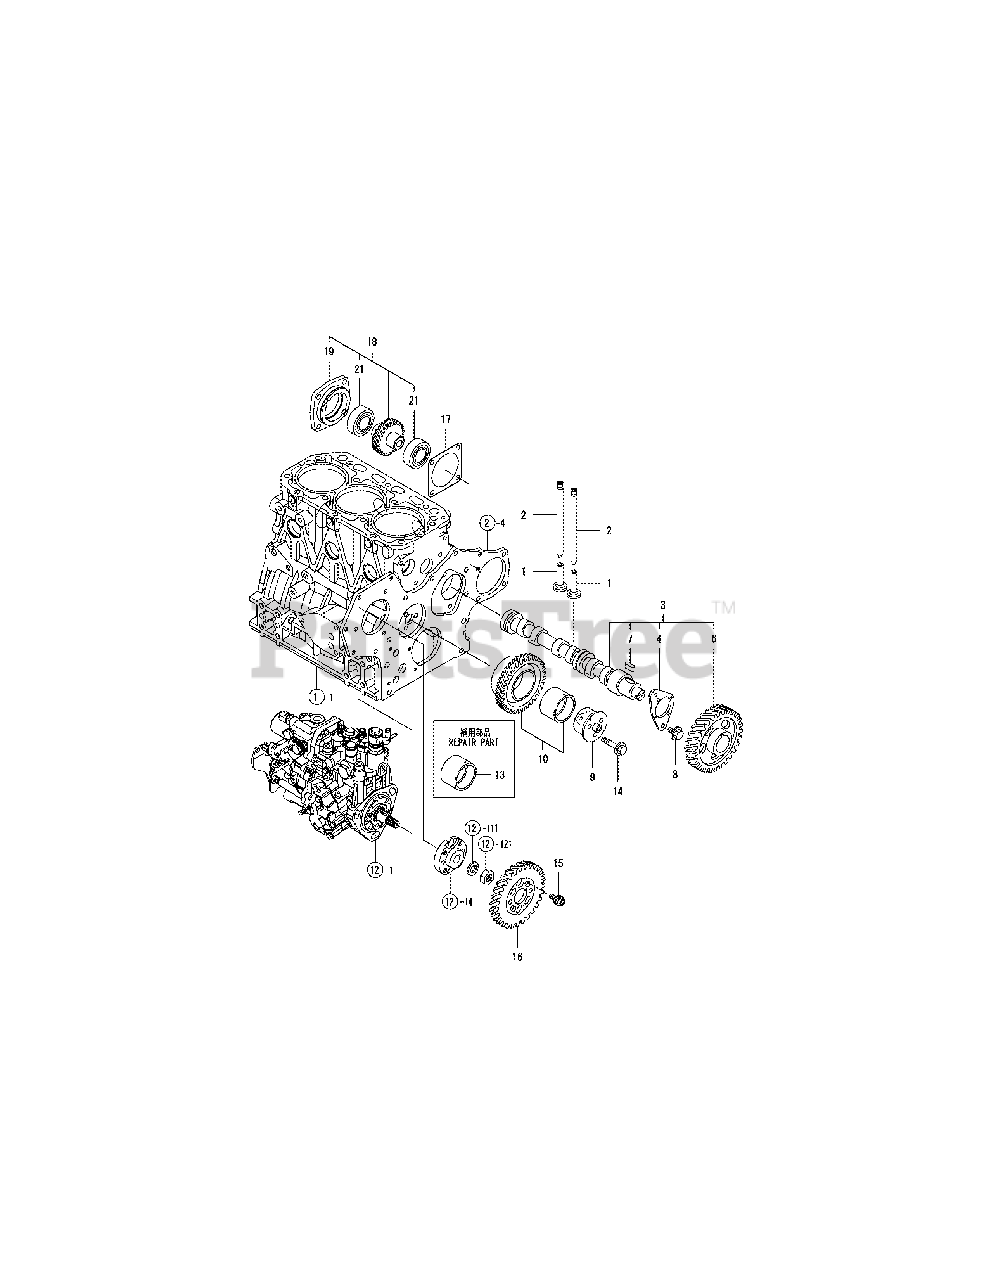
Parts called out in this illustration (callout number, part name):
6	GEAR, CAMSHAFT
8	BOLT 8X 14 PLATED
10	GEAR ASSY, IDLE
13	BUSH, IDLE GEAR
14	BOLT M 8X 40 PLATED
17	GASKET, (NON ASB.)
18	DRIVE ASSY, PUMP
